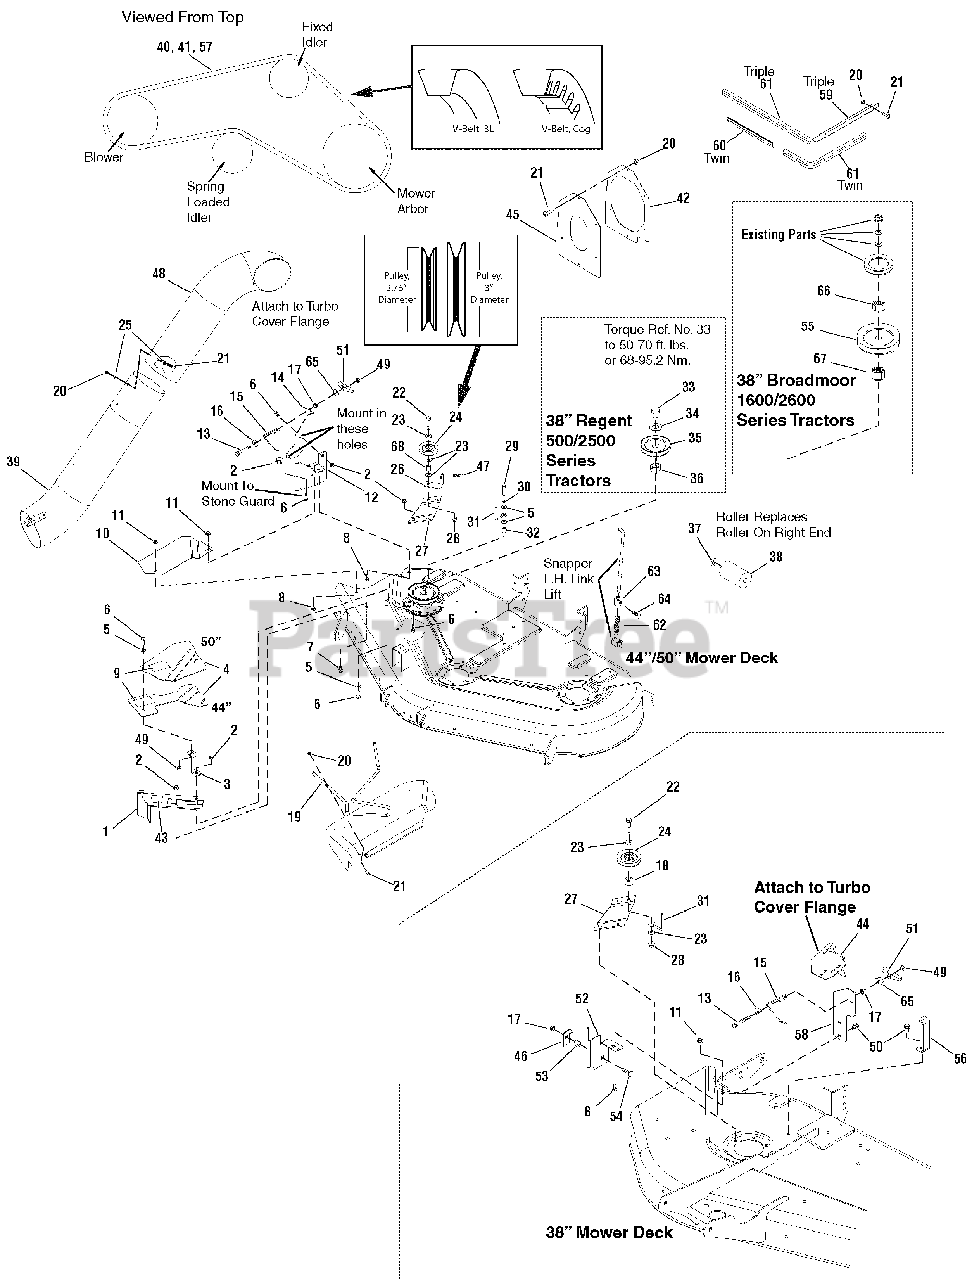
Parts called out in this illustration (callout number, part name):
1	PIVOT BRACKET ASSEMBLY
2	NUT, Hex Whiz Lock Flange, 5/16 - 18
3	SUPPORT, Belt Cover
4	COVER, Belt, 44"
4	COVER, Belt, 50"
5	WASHER, Flat, 5/16
6	CAPSCREW, Hex, 5/16 - 18 x 7/8
7	BOLT, Carriage, 5/16 - 18 x 3/4
8	BOLT, Carriage, 1/4 - 20 x 3/4
9	DECAL, Warning
10	COVER, Mower
11	NUT, Keps Conical, 1/4 - 20
12	BRACKET, Baffle
13	CAPSCREW, Hex, 5/16 - 18 x 2-1/2
14	BAFFLE, Turbo
15	SPRING, Latch
16	WASHER, 5/16
17	NUT, Keps Lock, 5/16 - 18
18	SPACER
19	ROD, Deflector
20	NUT, ESNA Lock, 10 - 24
21	SCREW, Truss Phillips, 10 - 24 x 3/4
22	CAPSCREW, Hex, 3/8 - 16 x 2
23	WASHER, Flat, 3/8
24	PULLEY, Idler, 2-3/4" Dia.
24	PULLEY, Idler, 3" Dia.
25	WASHER, Flat
26	BRACKET, "L"
27	BRACKET, "Z"
28	NUT, Whiz Lock Small, 3/8 - 16
29	CAPSCREW, Hex, 5/16 - 18 x 1-1/2
30	LOCKWASHER, 5/16
32	SPACER
33	NUT, 1-7/32 Sleeve Length
33	NUT, 1-3/4 Sleeve Length
34	WASHER, Flat, 7/8
35	PULLEY, 4.3
36	HUB, 0.73L
36	HUB, 1.28L
37	NUT, Push
38	ROLLER
39	TUBE ASSEMBLY, Lower
40	V-BELT, 3L, 37.90
40	V-BELT, Cog, 37.90
41	V-BELT, 3L, 37.90
41	V-BELT, Cog, 39.62
42	SEAL, Flange
43	*DECAL, Patent
44	LATCH - 38" Turbo
45	SEAL, Cover
46	BRACKET, "L" Turbo
47	PIN, Klik
48	TUBE, Upper
49	NUT, ESNA, 5/16 - 18
50	SCREW, 5/16 - 18 x 5/8
51	WINGNUT
52	DEFLECTOR
53	SPACER
54	BOLT, Carriage, 5/16 - 18 x 1 1/4
55	PULLY
56	STOP - UP BRACKET
57	V-BELT, 3L, 47.70
57	V-BELT, Cog, 47.875
58	BRACE, Turbo
59	PLATE, Deflector
60	SEAL, Rubber
61	SEAL, Rubber
62	SPRING, Compression
63	COLLAR, Locking
64	SCREW, Set, 5/16 - 19
65	WASHER, Spring Cup
66	HUB, PULLY, 0.681D x 1.50OD x 1.24LG
67	HUB, PULLY, 0.681D x 1.50OD x 1.65LG
68	SPACER, 5/8" O.D., 17/64" Long
69	KIT, Belt & Pulley, 38" Mower Decks
70	KIT, Belt & Pulley, 44" Mower Decks
71	KIT, Belt & Pulley, 50" Mower Decks
